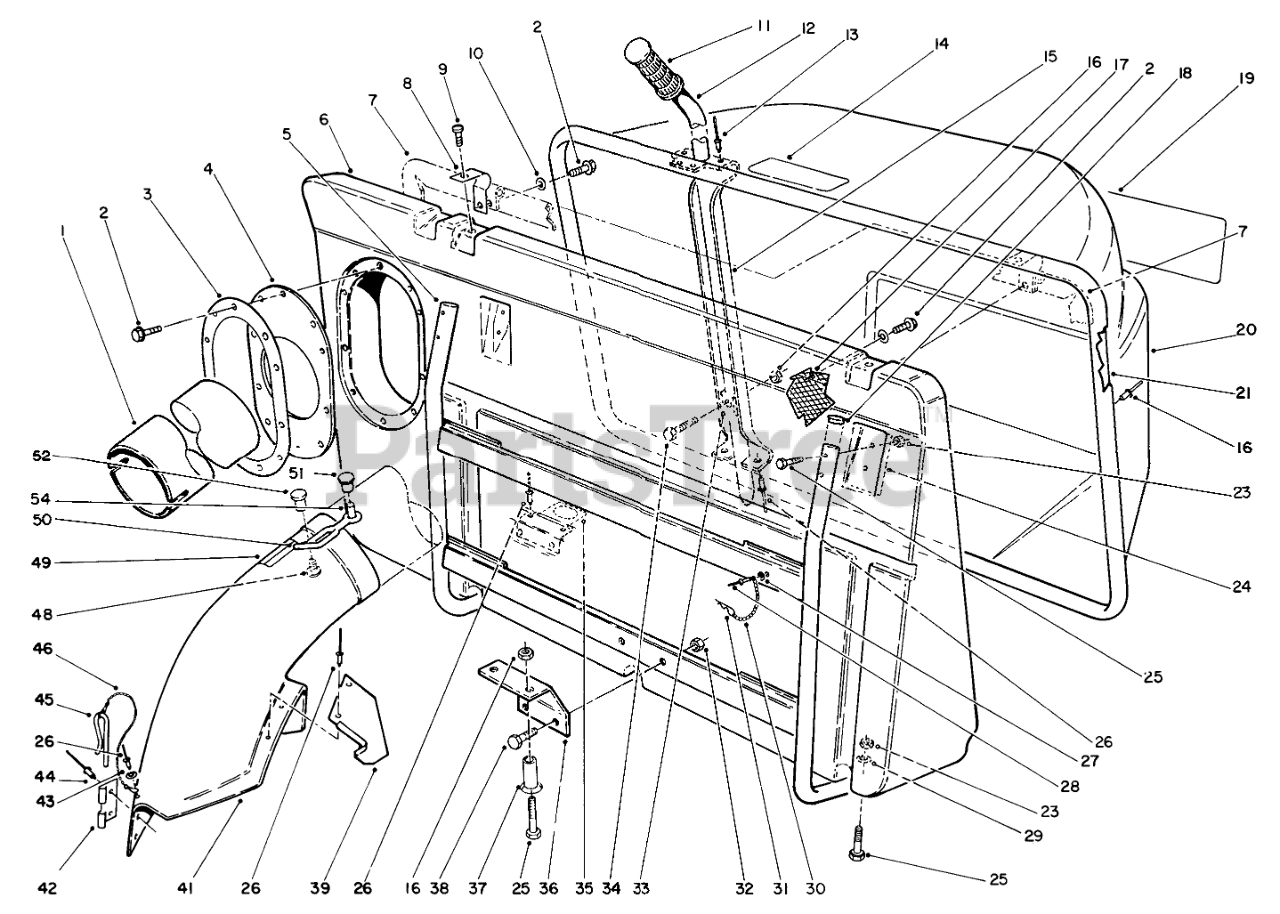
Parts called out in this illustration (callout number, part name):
1	Duct
2	SCREW-HWHTF
3	RING-RETAINING
4	RING-RETAINER, RUBBER
5	Frame
6	BAG-FRONT
7	SEAL-BAG
8	Bracket-Hinge
9	SCREW-HH
10	WASHER-FLAT
11	GRIP-HANDLE
12	HANDLE-DUMP
13	RIVET-POP
14	Decal Warning
15	Channel-Dump Handle
16	NUT-LOCK, NI
17	Screen Bag
19	DECAL - TORO
20	BASKET-GRASS
21	Frame-Grass Basket
23	NUT-LOCK, NI
24	Plate-Backup
25	SCREW-HH
26	RIVET-BLIND
27	WASHER
29	WASHER-FLAT
30	10 LINK CHAIN W/O HOOK
31	PIN-HAIR
32	NUT-LOCK, NI
33	GUIDE-HANDLE, DUMP
34	SCREW-HH
35	Latch
36	Bracket-Hitch
37	Spacer
38	SCREW-HH
39	CHUTE SUPT BRKT
41	Chute Ass-y. (Incl. Ref. #26, 39, 42-49, 52 & 54)
42	BRACKET-MOUNTING, CHUTE
43	WASHER-PLAIN
44	RIVET-BLIND
45	PIN-LOCKING, CHUTE
46	LANYARD
48	Screw
49	DECAL-DANGER
50	RETAINER-DUCT
51	SPACER-INTERLOCK
54	FASTENER-PANEL
